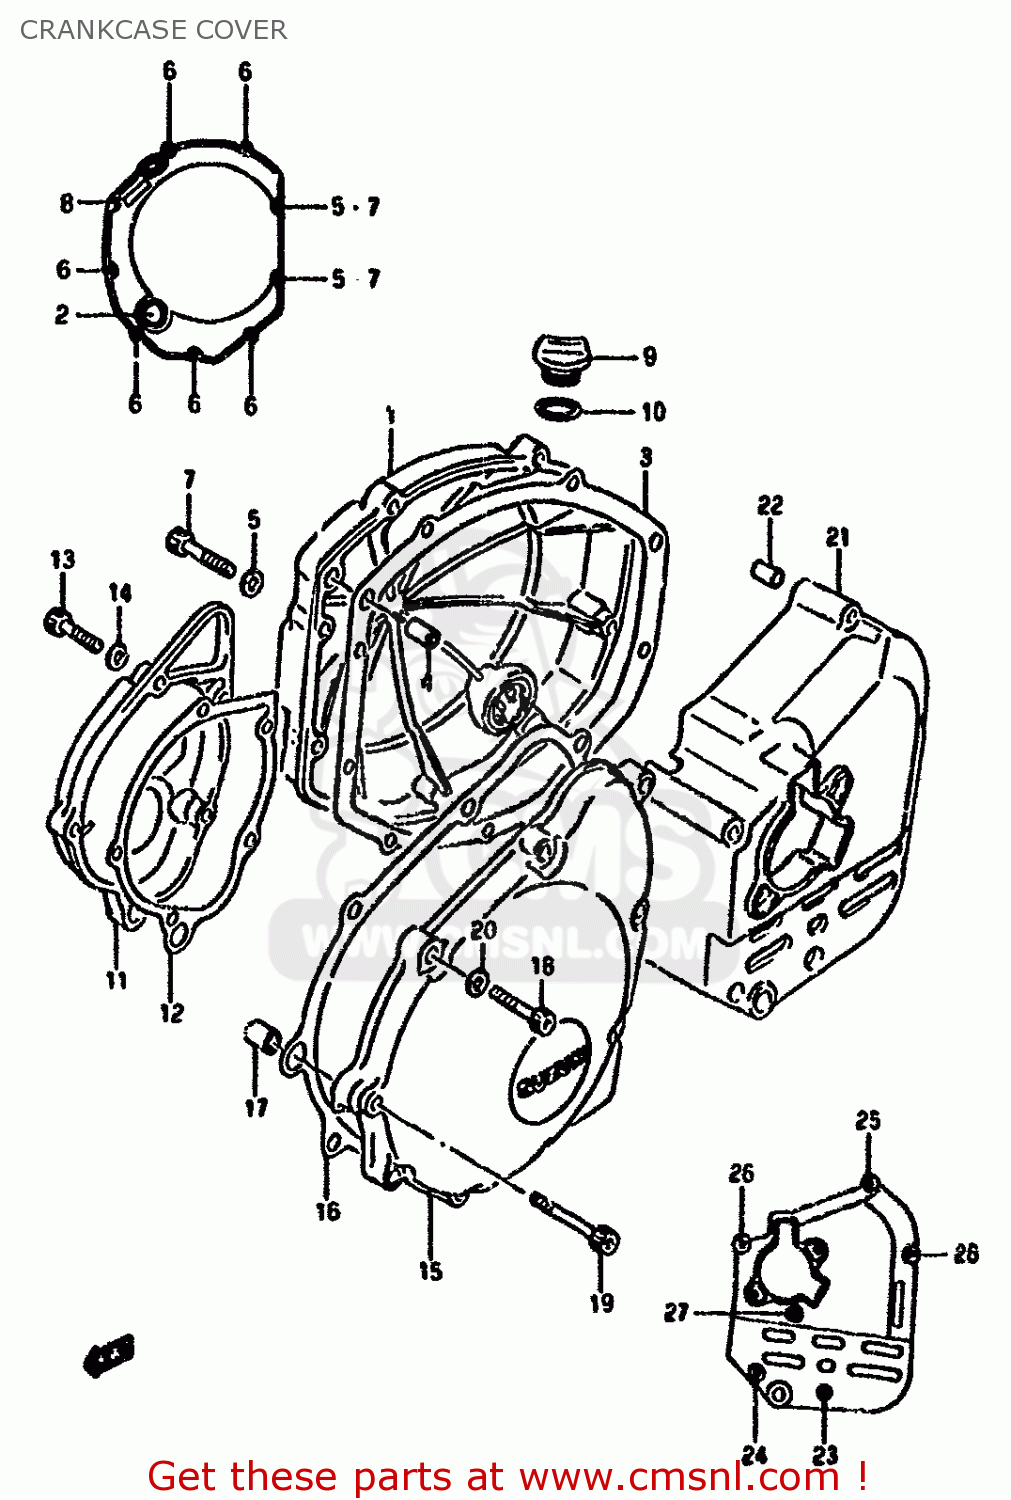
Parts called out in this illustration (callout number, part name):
1	COVER,CLUTCH
2	LENS,OIL LEVEL CHECK
3	GASKET,CL COVER (NAS)
4	PIN
5	GASKET(5.8X11X1.2) (NAS)
6	BOLT
7	BOLT
8	BOLT
9	PLUG
10	O RING(D:3.1,ID:16.8)
11	COVER,SIGNAL GENERATOR
12	GASKET,SIGNAL GENERATOR COVER (NAS)
13	BOLT
14	GASKET(5.8X11X1.2) (NAS)
15	COVER,STARTER GEAR
16	GASKET,STARTER GEAR COVER (NAS)
17	PIN (11X20)(SUS)
18	BOLT
19	BOLT
20	GASKET(5.8X11X1.2) (NAS)
21	COVER,SPROCKET
22	PIN
23	BOLT
24	BOLT
25	BOLT
26	BOLT
27	BOLT
